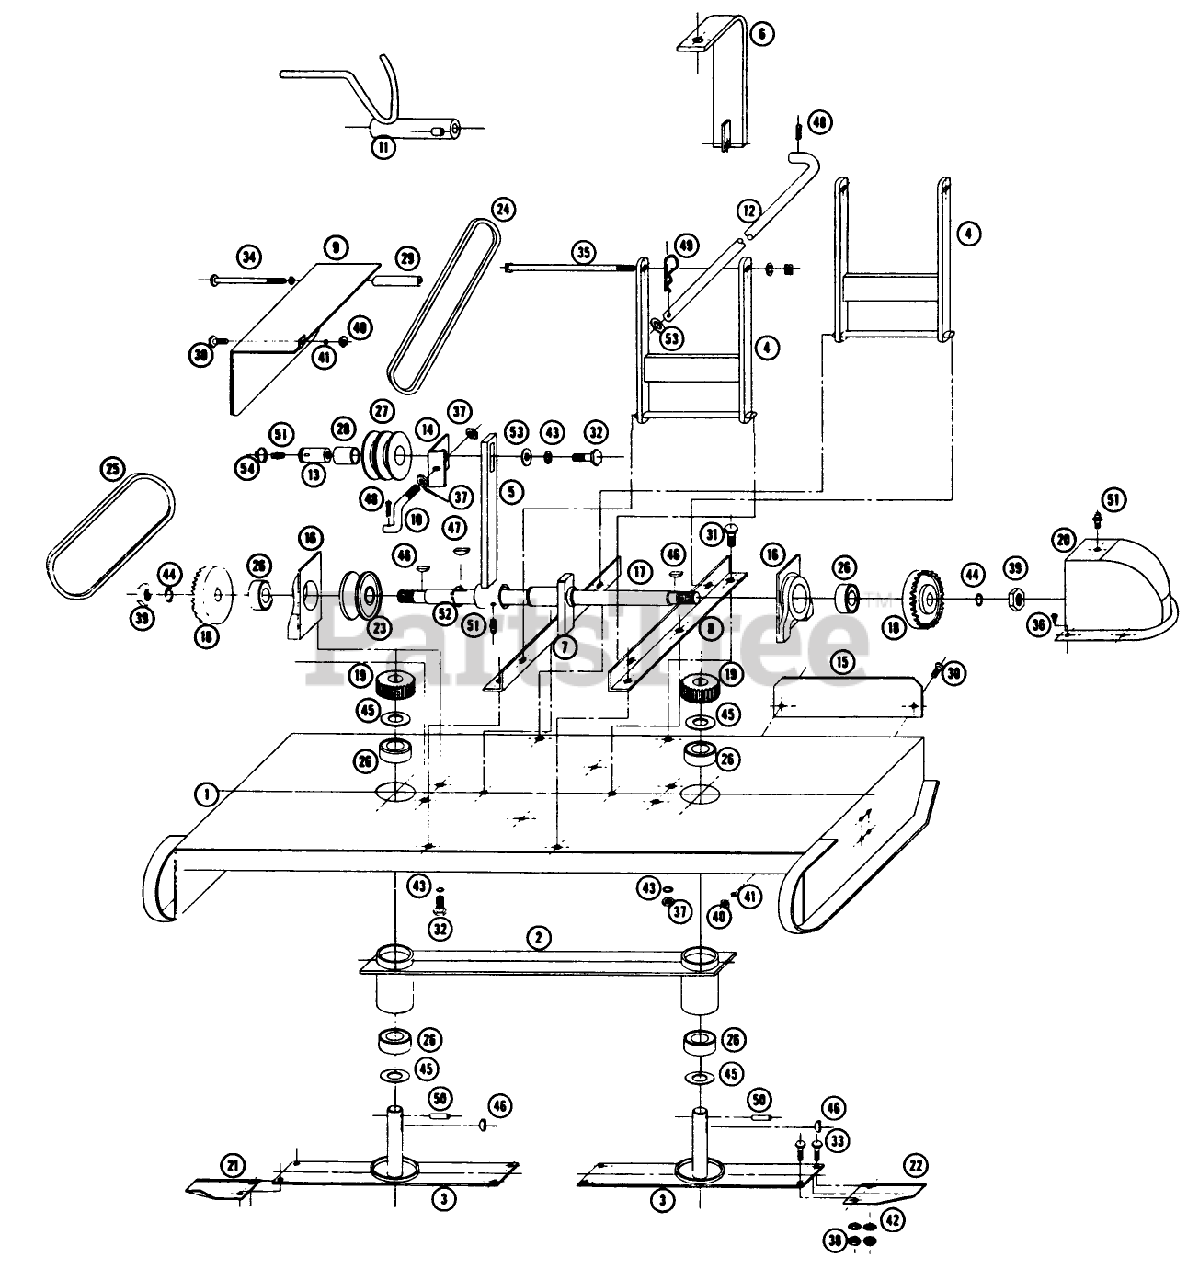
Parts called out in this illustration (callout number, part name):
2	Pin-Dowel
16	BEARING SUPPORT
17	SHAFT CROSS
18	Gear
19	SPUR GEAR
20	COVER GEAR
23	PULLEY
26	Ball
28	Bronze Bearing
30	Hex Head Cap
31	Hex Head Cap
32	Hex Head Cap
36	Stove Bolt
37	Hex Nut
38	Grip
40	Hex Nut
41	Lockwasher, 1/4
42	Lock Washer 5/16
43	Lockwasher
44	Washer-Lock 5/8
45	Flat Washer
46	Key #5
47	Key-#9
48	Cotter Key
49	Hair Pin Cotter
50	Roll Pin
51	Zerk
52	PART CAT 1967 OPC
53	SPRING,2X3 SS
54	Snap Ring
